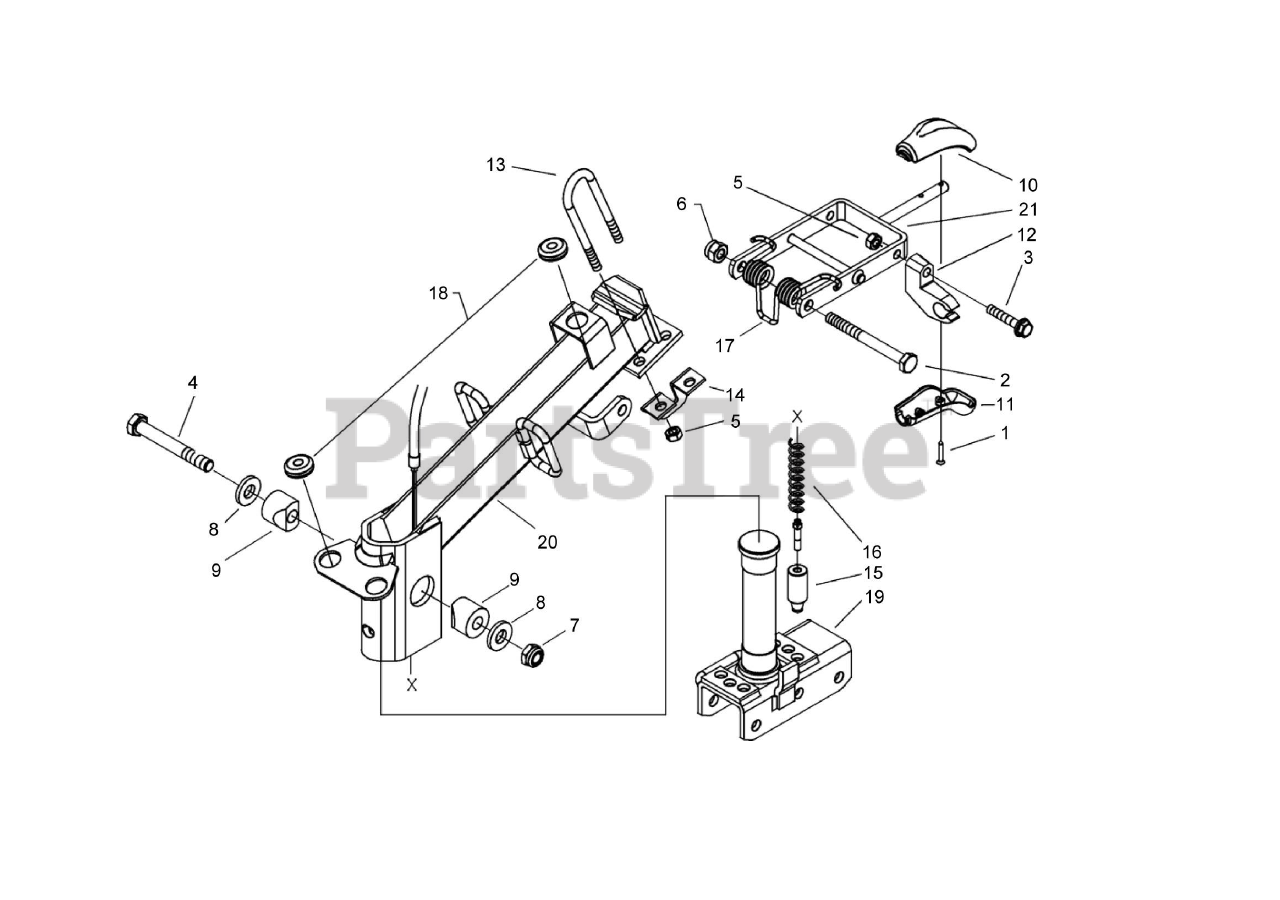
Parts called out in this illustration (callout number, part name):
1	SCREW 3.5X25
2	CAPSCREW M10X110 UNI 5737-8G
3	SCREW
4	CAPSCREW M12X80 UNI 5737-8G
5	LOCKNUT M8 STANDARD DIN985ZC
6	LOCKNUT M10 STANDARD DIN 985ZC
7	LOCK NUT M12 DEFORMED
8	SPRING WASHER
9	WEDGE
10	UPPER HDLE.REL.KNOB BLACK
11	LOWER HDLE.REL. KNOB BLACK
12	SUPPORT, CONTROL ROD
13	U BOLT
14	BRACKET
16	SPRING, STEERING COLUMN
17	SPRING, RELEASE HDLE BAR
18	SUPPORT CAP, BODY GUARD
19	CONNECTION
20	COLUMN
21	LEVER, HANDLE BAR SELECTION
